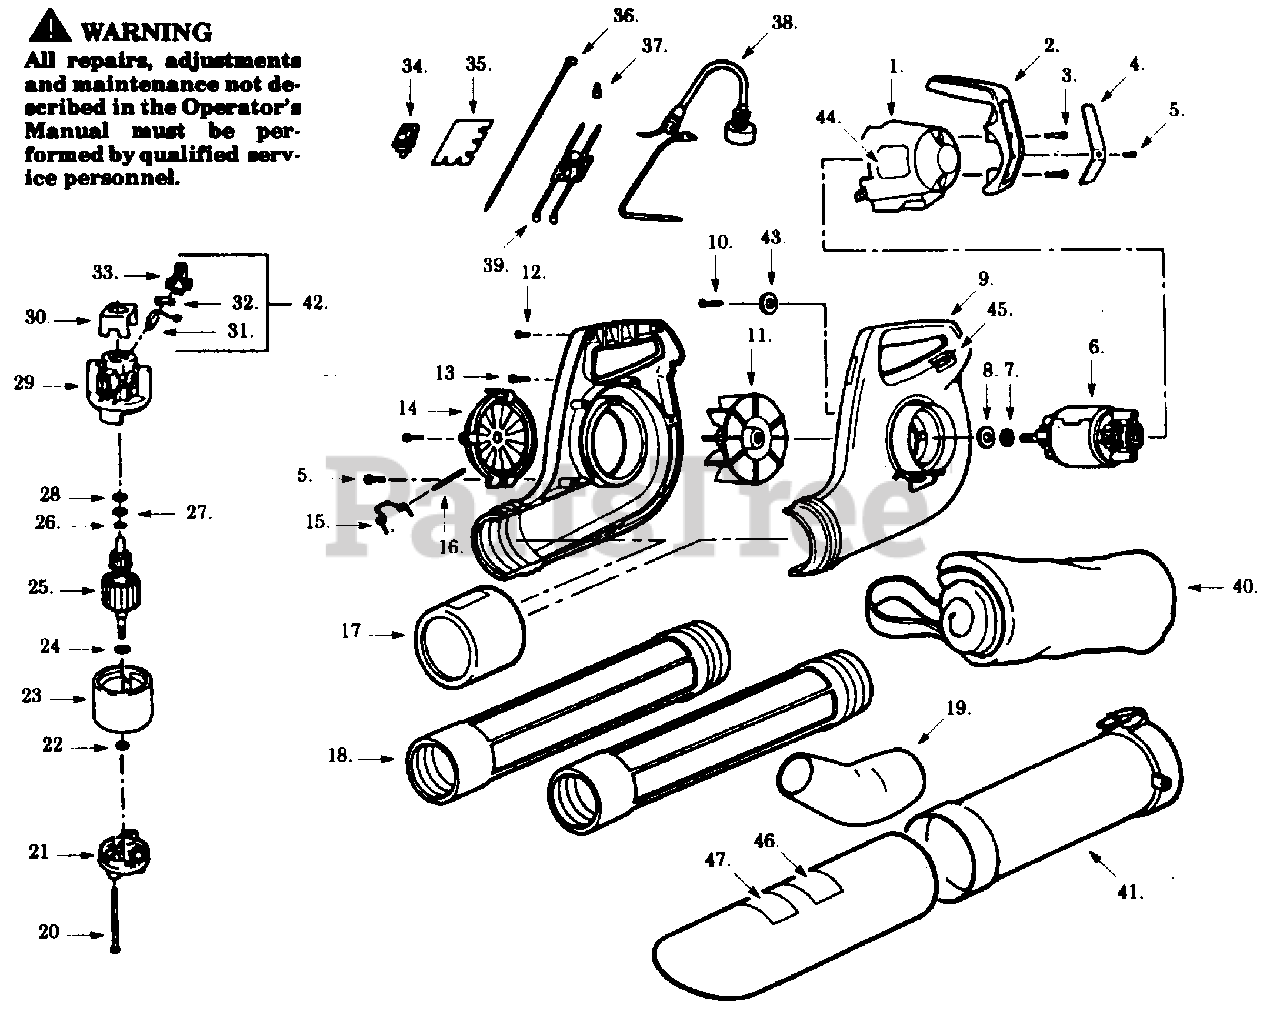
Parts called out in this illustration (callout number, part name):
1	Motor Cover
4	Plate Warning
7	Retaining Ring
9	L.H/R.H. Housing
11	Impeller Ass'y.
14	Inlet Cover
16	Hinge Pin
17	Ferrule Sleeve
18	Outlet Tube
19	Curved Nozzle
21	Endbell Ass'y. (Drive)
23	Field Ass'y.
24	Retaining Ring
25	Armature Ass'y.
26	Retaining Ring
29	Endbell Ass'y. (Brush)
30	Insulator
32	Brush Spring
33	Brush Holder
34	On-Off Switch Ass'y.
35	Mounting Board
36	Leadwire Ass'y.
37	Wire Nut
38	Power Cord Ass'y.
39	P.C. Board Ass'y.
40	Vacuum Bag
41	Vacuum Tube
42	Brush Kit (Incl. 31-33)
44	Motor Cover Label (Not a serviceable part)
45	Switch Position Label
46	Name Plate Label (Not a serviceable part)
47	Warning Label
